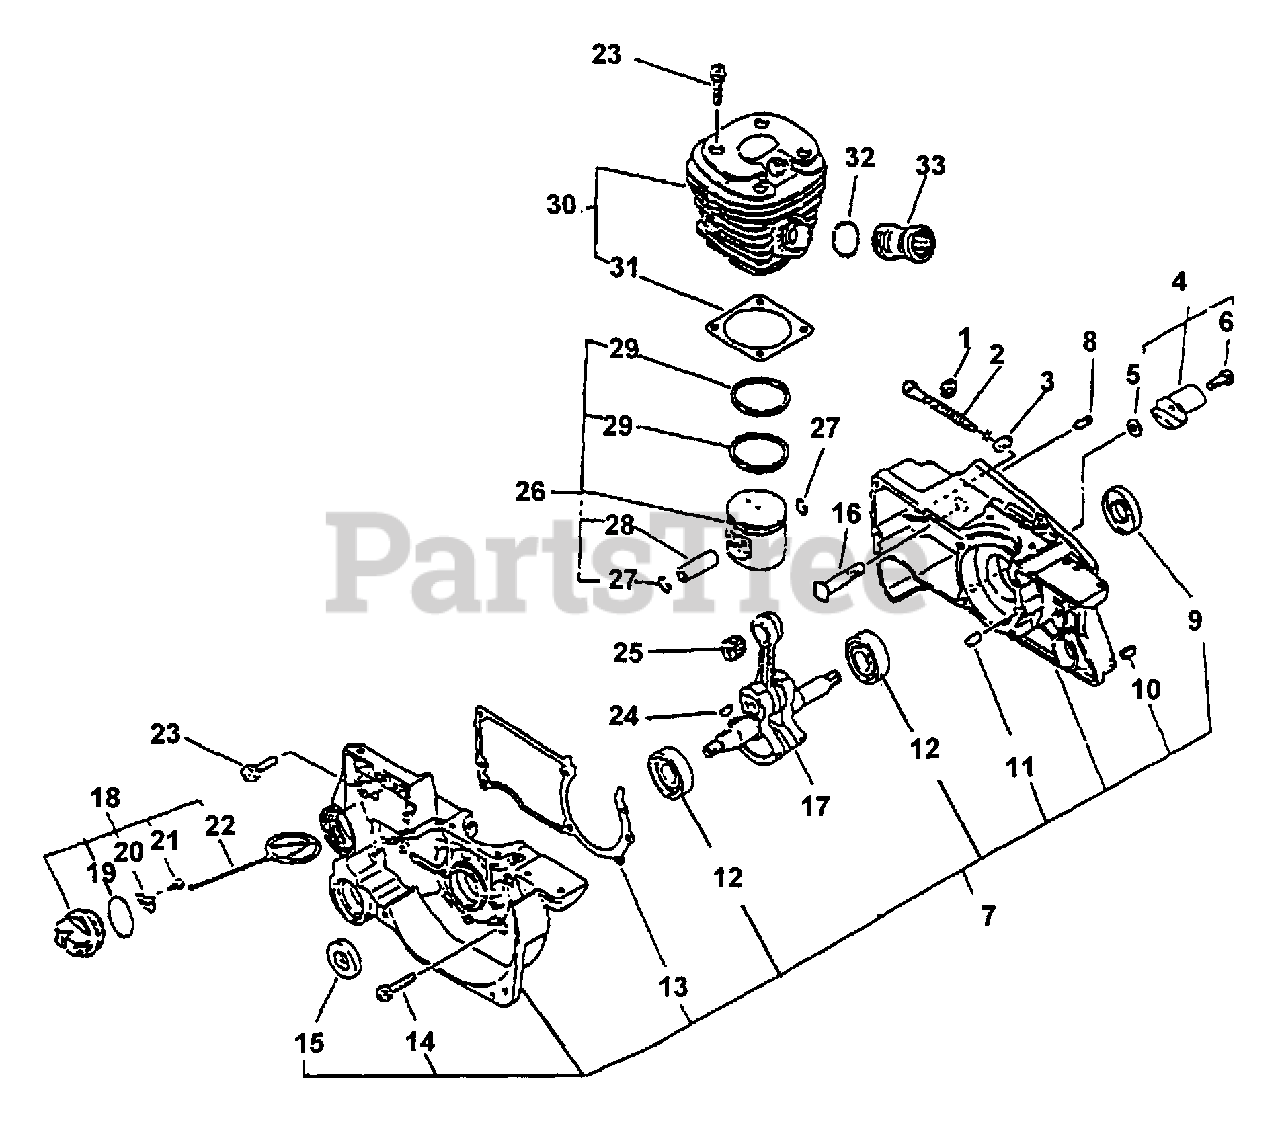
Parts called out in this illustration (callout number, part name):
2	SCREW, TENSIONER
3	TENSIONER, CHAIN
4	CHAIN CATCHER KIT
5	WASHER - 5
6	SCREW - 5X18
7	CRANKCASE KIT
8	VENT, TANK
9	SEAL, OIL
10	PIN - SPRING -- 5X10
11	PIN - LOCATING
12	BEARING, BALL - 6202
13	GASKET, CRANKCASE
14	SCREW - 5X30
15	SEAL, OIL
16	STUD, GUIDE BAR
17	CRANKSHAFT ASSY
18	CAP ASSY
19	O-RING - 25
20	RETAINER
21	SCREW - 3X8
22	CONNECTOR, CAP
23	SCREW - 5X20
25	BEARING, NEEDLE
26	PISTON KIT
27	RING, RETAINING - 8
28	PIN, PISTON
29	RING, PISTON
30	CYLINDER KIT
31	GASKET, CYLINDER
32	BAND
33	ADAPTOR, INTAKE
